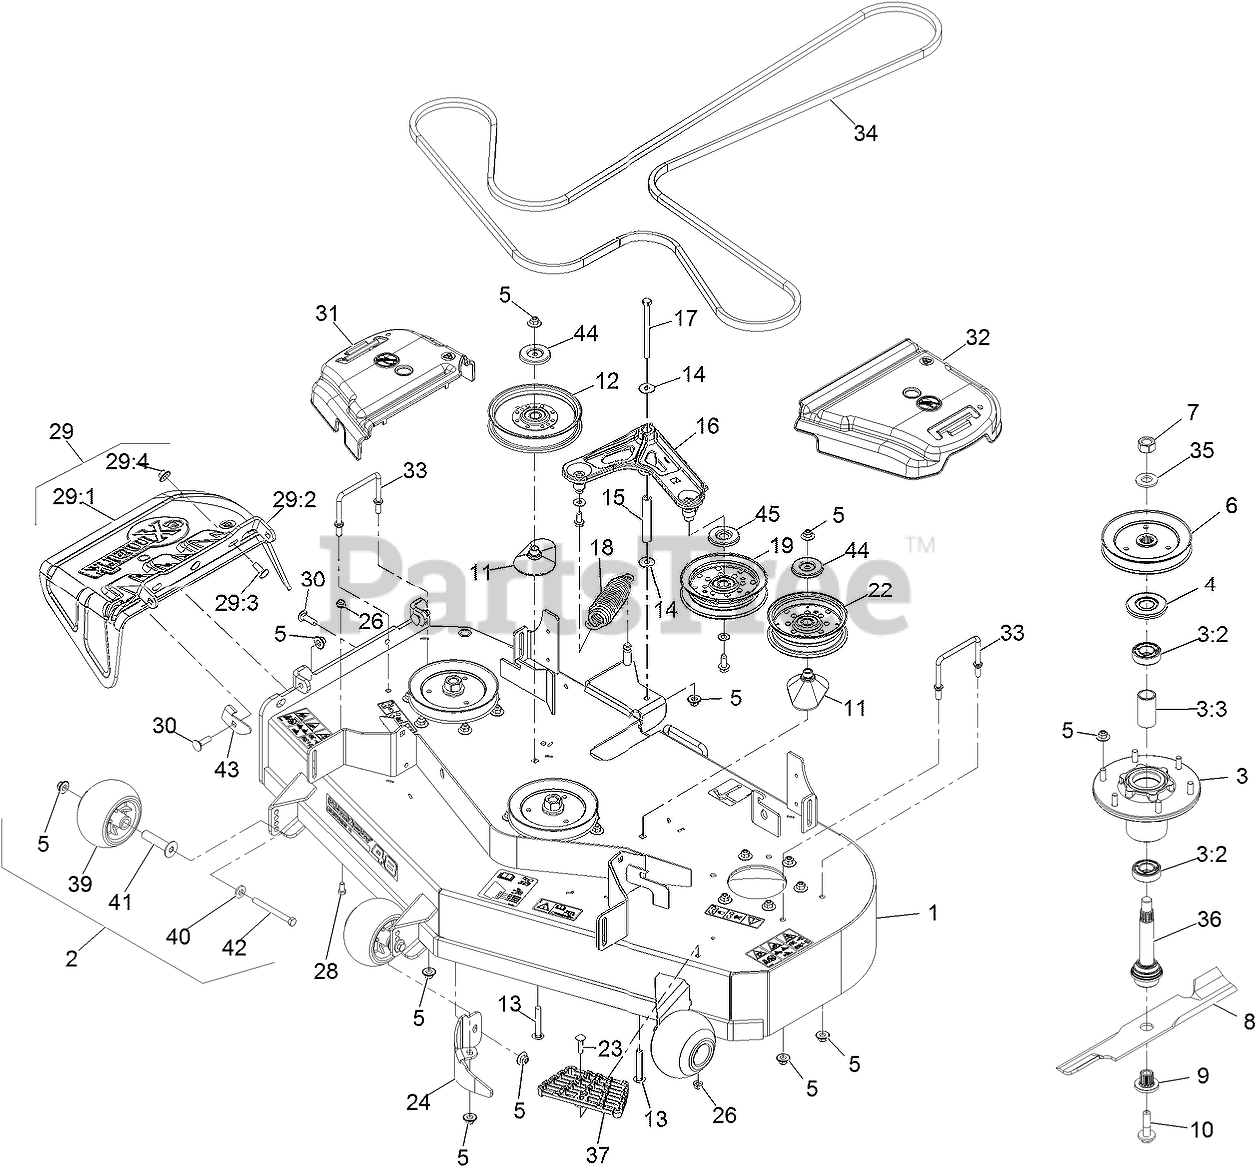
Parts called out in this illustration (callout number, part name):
1	ASM-DECK W/DECALS 484
2	KIT, ANTI-SCALP ROLLER
3	ASM-CUTTER HSG WITH BEARINGS
3:2	BEARING-BALL
3:3	SPACER-BEARING
4	GUARD,BEARING TOP .989
5	Nut-Nyloc 3/8-16 Flg
6	SHEAVE,BLADE DRIVE 5.90
7	NUT-HEX
9	BUSHING,SPLINED
10	SCREW,SEMS 1/2-20 X 2.19
11	SPACER-PULLEY
12	IDLER-PULLEY, FLAT 6.00X1.00
13	SCREW-CARR
15	BUSHING
16	IDLER ARM ASM
17	SCREW-HH
18	SPRING-EXTENSION
19	IDLER-PULLEY, FLAT
22	IDLER-PULLEY, FLAT 5.00X1
23	Bolt-Carriage 5/16-18 X 1 1/4
24	BAFFLE-DOGLEG,LZS LZX VT48
26	NUT-HF, NI
28	SCREW-HH
29	ASM,DISCHARGE CHUTE
29:1	CHUTE,DISCHARGE
29:2	BRACKET,DISCHARGE CHUTE
29:3	SCREW-CARR
29:4	Nut-Nyloc 3/8-16 Flg
30	BOLT-CARR
31	COVER-BELT, RH
32	COVER-BELT, LH
33	WIREFORM-COVER
36	ASM-SPINDLE AND SEAL
37	STEP-DECK
39	ROLLER-SCALP, ANTI
40	WASHER-BELLEVILLE
41	AXLE, ROLLER
42	SCREW-HH 3/8-16 X 3 3/4 GR 8
43	STOP-DISCHARGE CHUTE
44	SHIELD-DUST
45	SHIELD-GUARD, DUST
